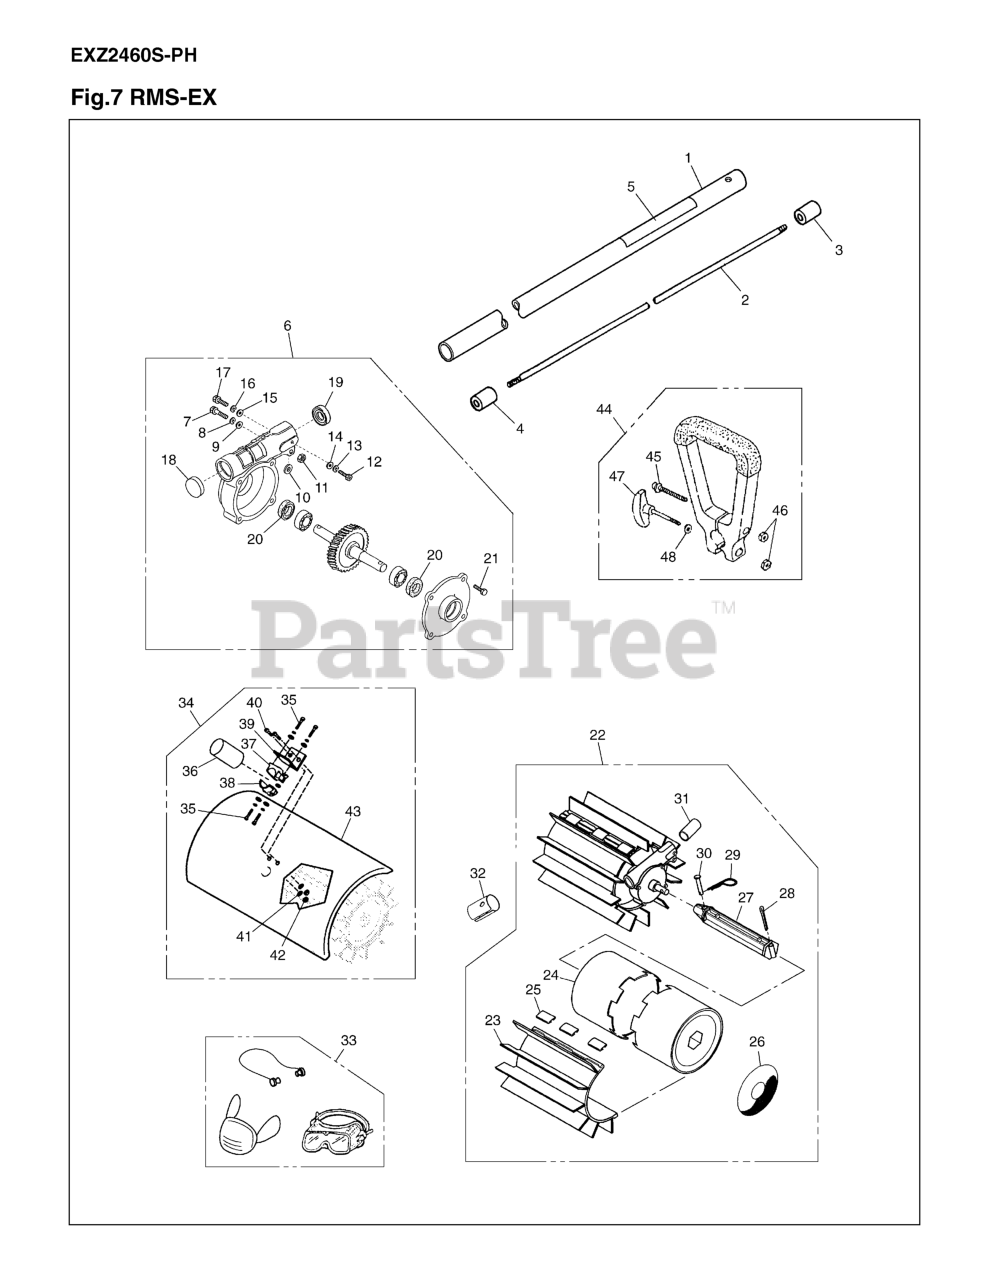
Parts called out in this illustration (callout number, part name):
1	PIPE COMP
3	JOINT, SHAFT (RP
4	SPACER
5	PLATE-NAME
6	GEAR CASE
7	BOLT, M6 x 30
8	SPRING WASHER
9	WASHER, FLAT
10	WASHER, FLAT
12	BOLT, M5 x 12
13	WASHER, SPRING M
14	WASHER, M5 x .8
15	WASHER, M5 x .8
16	WASHER, SPRING M
18	PLUG, HOUSING
19	OIL SEAL (REPLAC
20	OIL SEAL (REPLAC
22	RMSZ-A(REDMAX BR
23	BELT, CLEAN SWEE
24	DRUM
25	BELT CLIP
26	LABEL, REDMAX
27	DRUM AXLE
28	COTTER PIN
29	HITCH PIN
30	CLEVIS PIN
31	TUBE PROTECTOR
32	SPACER
33	SAFETY KIT
34	SHIELD, DEBRIS (
37	BRACKET, HANDLE
38	CAP, LOWER
39	BRACKET, SHIELD
43	SHIELD, DEBRIS (
44	HANDLE ASSY (RPL
